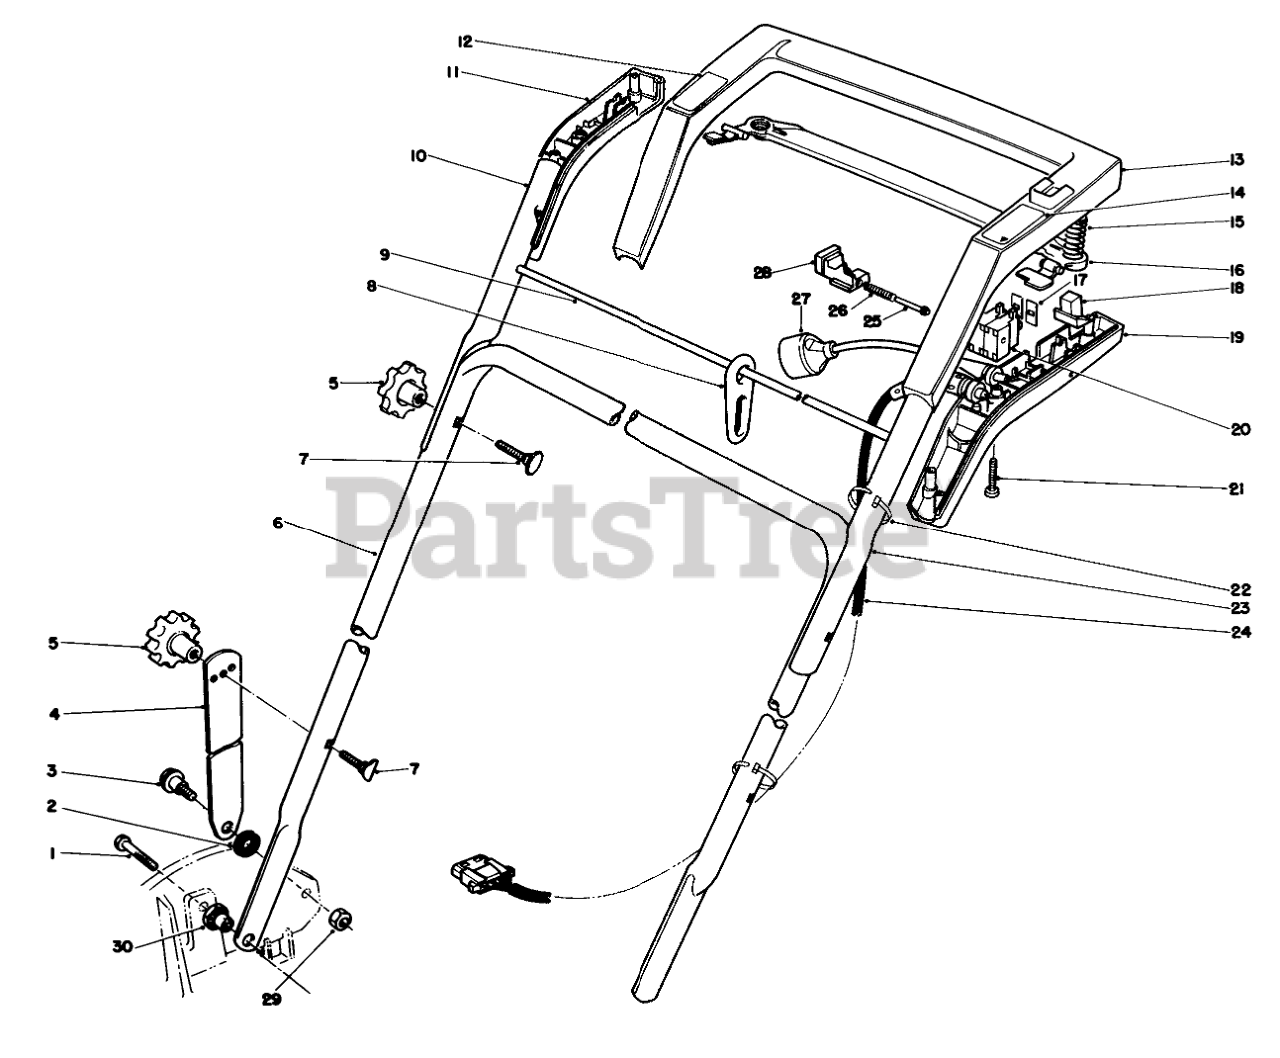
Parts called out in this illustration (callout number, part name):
1	SCREW-HH
2	SPACER
3	SCREW-SHOULDER
4	Handle Latch
6	LOWER HANDLE
7	5/16-18 X 2 HNDLE SCREW
8	CORD MINDER
9	CORD MINDER ROD
10	UPPER HDLE TUBE RH
11	RH GRIP COVER
12	Decal-Handle, Warning
13	HAND GRIP/DECALS
14	ON/OFF DECAL
15	COMP SPRING
16	SQUEEZE LEVER
17	DUST COVER
18	SWITCH BUTTON
19	LH GRIP COVER
20	ON/OFF SWITCH
21	SCREW-PPH
22	Cable Tie
23	UPPER HDLE TUBE LH
24	WIRE HARNESS
25	BUTTON GUIDE
26	COMPRESSION SPRING
27	POWER SUPPLY CORD
28	INTERLOCK BUTTON
29	NUT-LOCK, NI
30	HANDLE PIVOT NUT
